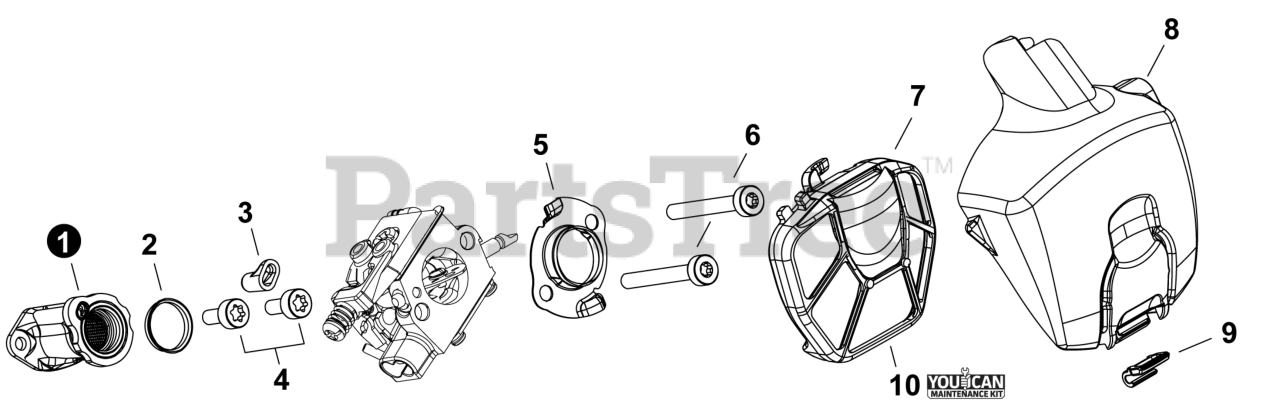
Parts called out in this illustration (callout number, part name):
1	BELLOWS, INTAKE
2	COLLAR 14
3	COLLAR 3
4	BOLT, TORX 4x10
5	ELBOW, CARBURETOR
6	BOLT, TORX 5x40
7	FILTER ASSY, AIR - NYLON MESH
8	COVER, AIR FILTER
9	RETAINER, AIR FILTER
10	TUNE-UP KIT - YOUCANT
